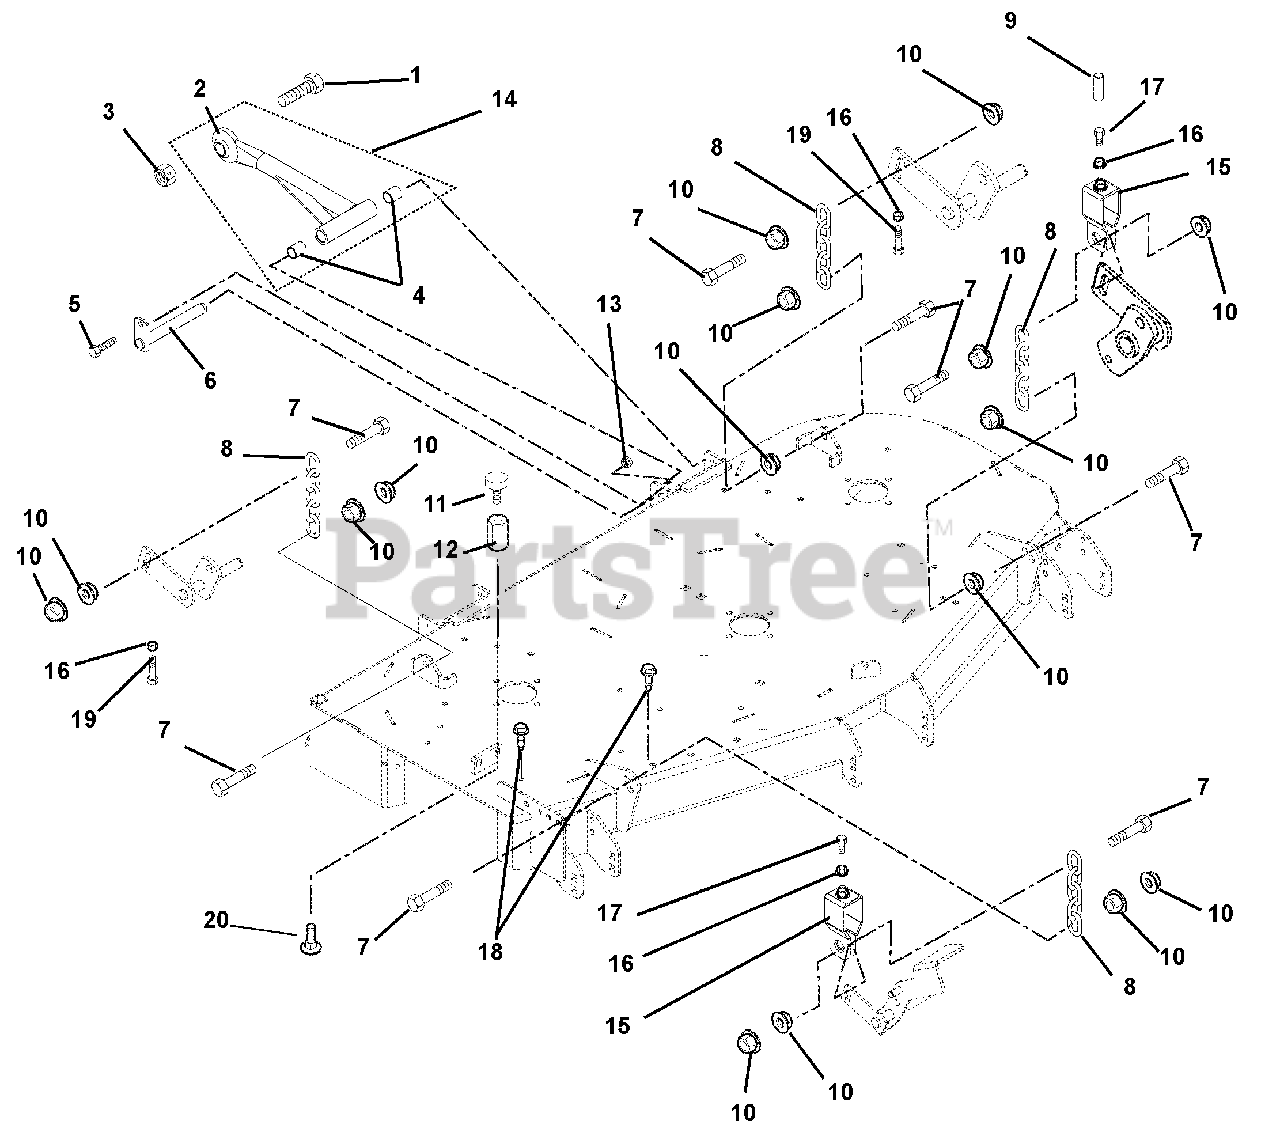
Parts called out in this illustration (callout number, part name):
1	Bolt, Hex .875-9 x 2.75 Grade 5
2	Mower Mounting Arm Weldment
3	Nut, Locking Center .875-9
4	Bearing, .75 x .875 x 1.00
5	Bolt, Hex .38-16 x .75 Grade 5
6	Weldment, Mower Mounting Pin
7	Bolt, Hex M12-1.75 x 50 Grade 5
8	Chain, Link
9	Cap, Vinyl .50ID x 1.50LG x .055
10	Nut, Spin Lock Flange M12-1.75
11	Bumper, Rubber
12	Coupling Nut, .31-18 x 3.00
13	Nut, .38-16 Nyloc Flange
14	Assembly, Mower Mounting Arm (Includes item # 2 and item # 4)
15	Bracket, Deck Leveling
16	Nut, Jam .312-18
17	Bolt, Hex .31-18 x 2.00 Full Thread
18	Screw, Tapping .38-16 x .50 Hex Washer Head Thread (992156)
19	Bolt, Hex .312-18 x 1.50 Grade 5
20	Bolt, Round Head Square Neck .31-18 x .75 Loc-Tite
